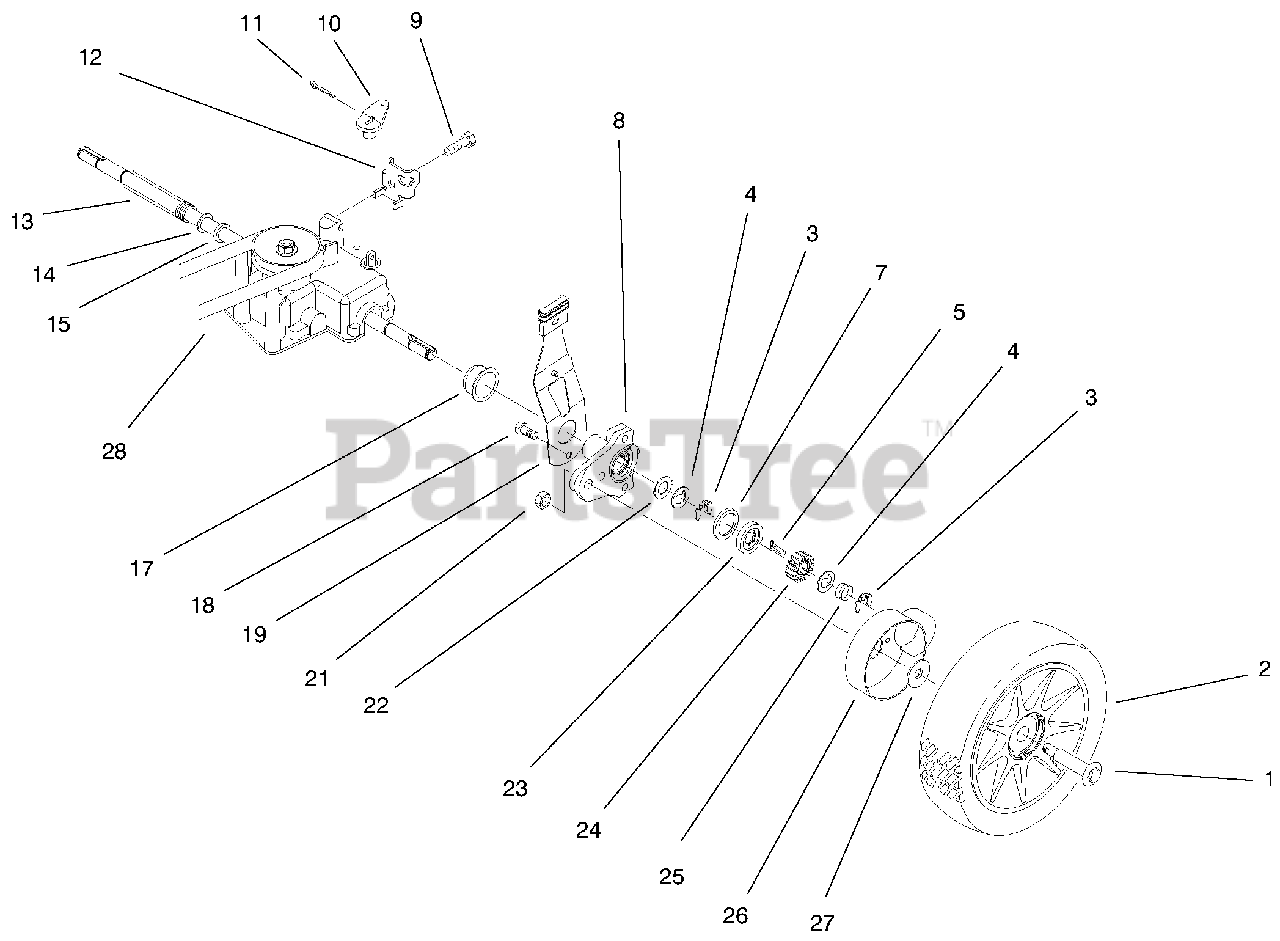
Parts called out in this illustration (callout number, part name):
1	Bolt-Shoulder
2	Wheel & Tire Ass'y-8"
3	Ring-Retaining
4	Washer-Thrust Keyed
5	Key-Rocking L.H.
7	Ring-Friction
8	Height Adj. Arm Ass'y-Rear
9	Screw-Tapping
10	Lever-Shift
11	Pin-Cotter
12	Retainer-Cable
13	Cover-Drive Shaft
15	Washer-Flat
18	Screw-Hex Hd. Cap
19	Spring Arm Ass'y-Rear L.H.
21	Nut-Lock
22	Washer-Thrust
24	Gear-Pinion
25	Spring-Compression
26	Cover-Wheel
27	Washer-Stepped
